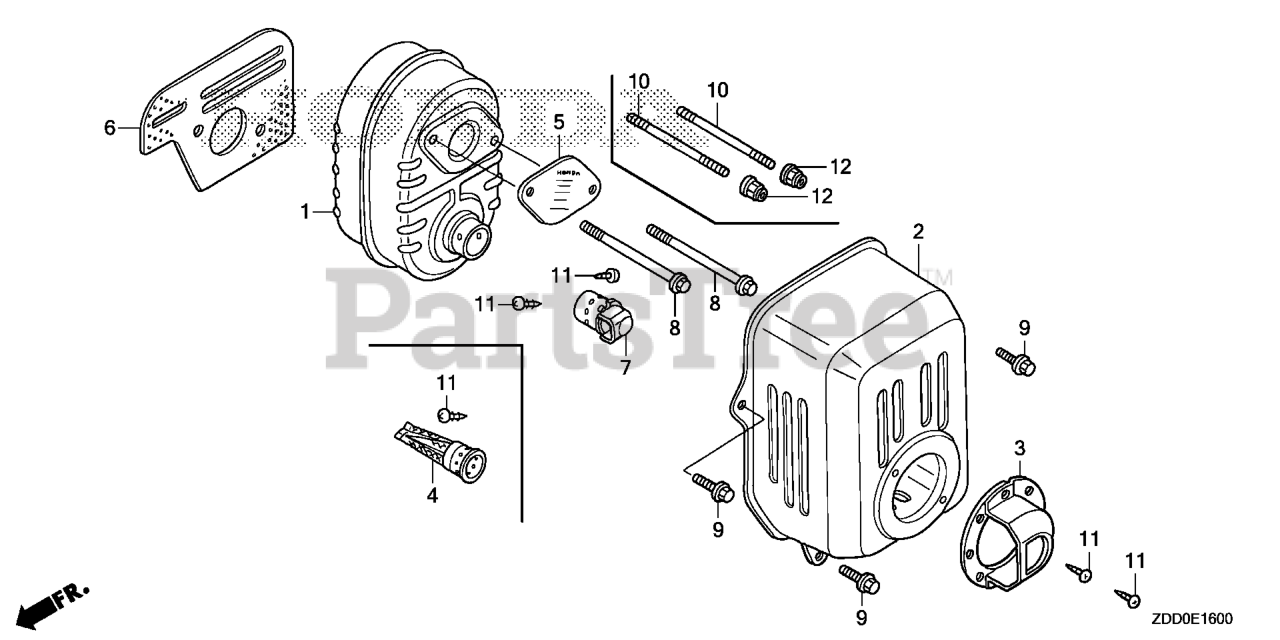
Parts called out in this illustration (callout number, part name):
2	PROTECTOR, MUFFLER
4	ARRESTER, SPARK (TO 1207644)
6	GASKET, MUFFLER
9	BOLT, FLANGE (6X14)
10	BOLT, STUD (6X78) (CT200)
11	SCREW, TAPPING (4X6) (TO INSTALL OPTIONAL SPARK ARRESTER)
12	NUT, SELF-LOCK (6MM)
